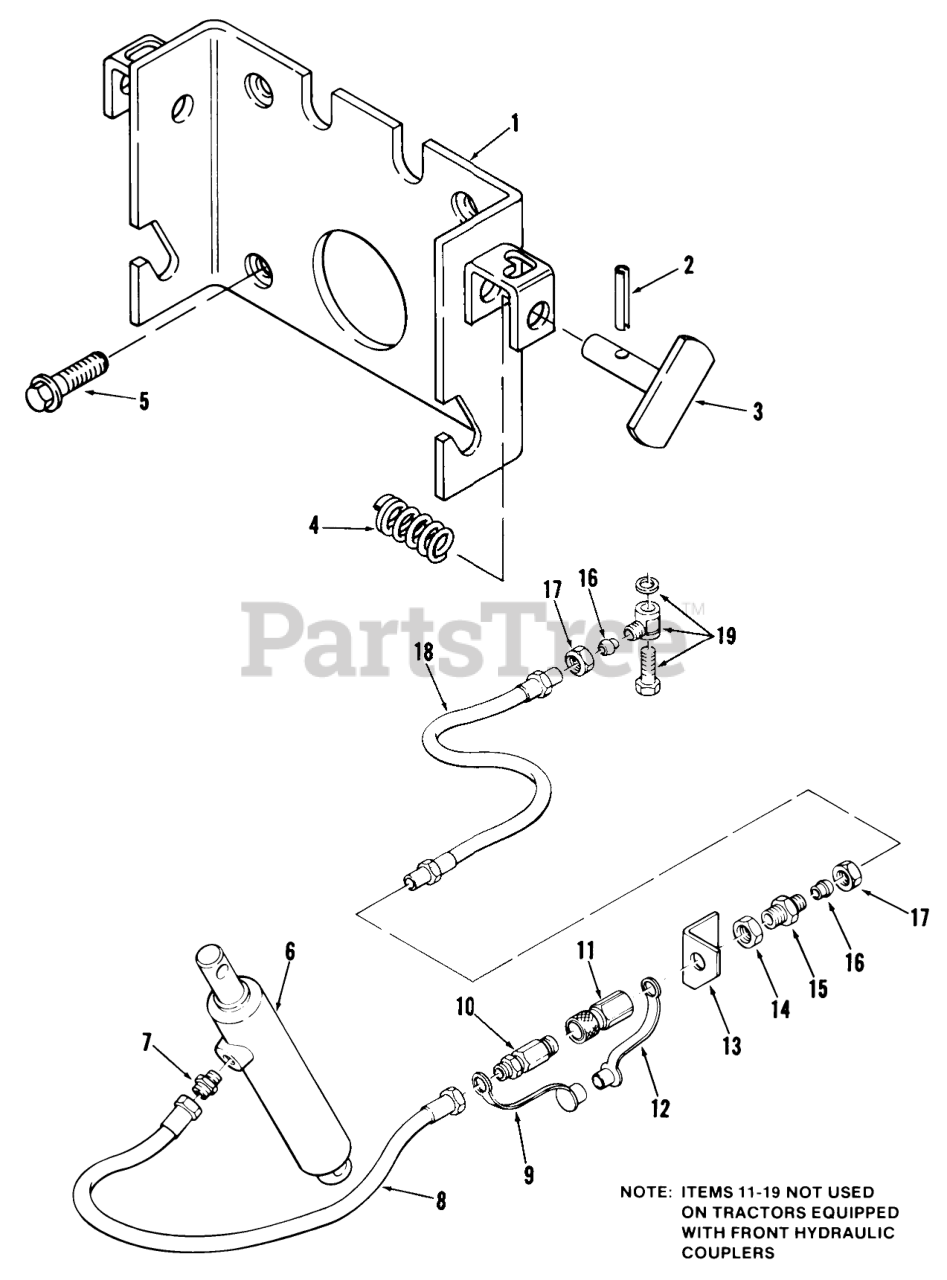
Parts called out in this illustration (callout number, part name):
1	Mounting Plate
2	Rollpin
3	Locking Pin
4	Spring
6	Hydraulic Cylinder
7	FITTING
8	Hydraulic Hose
9	DUST CAP
10	Coupling Plug
11	Q.D. Fitting
12	Dust Cap
13	Mounting Plate
15	Fitting
16	RING SEAL
19	JOINT (CONSISTS 2 PT
